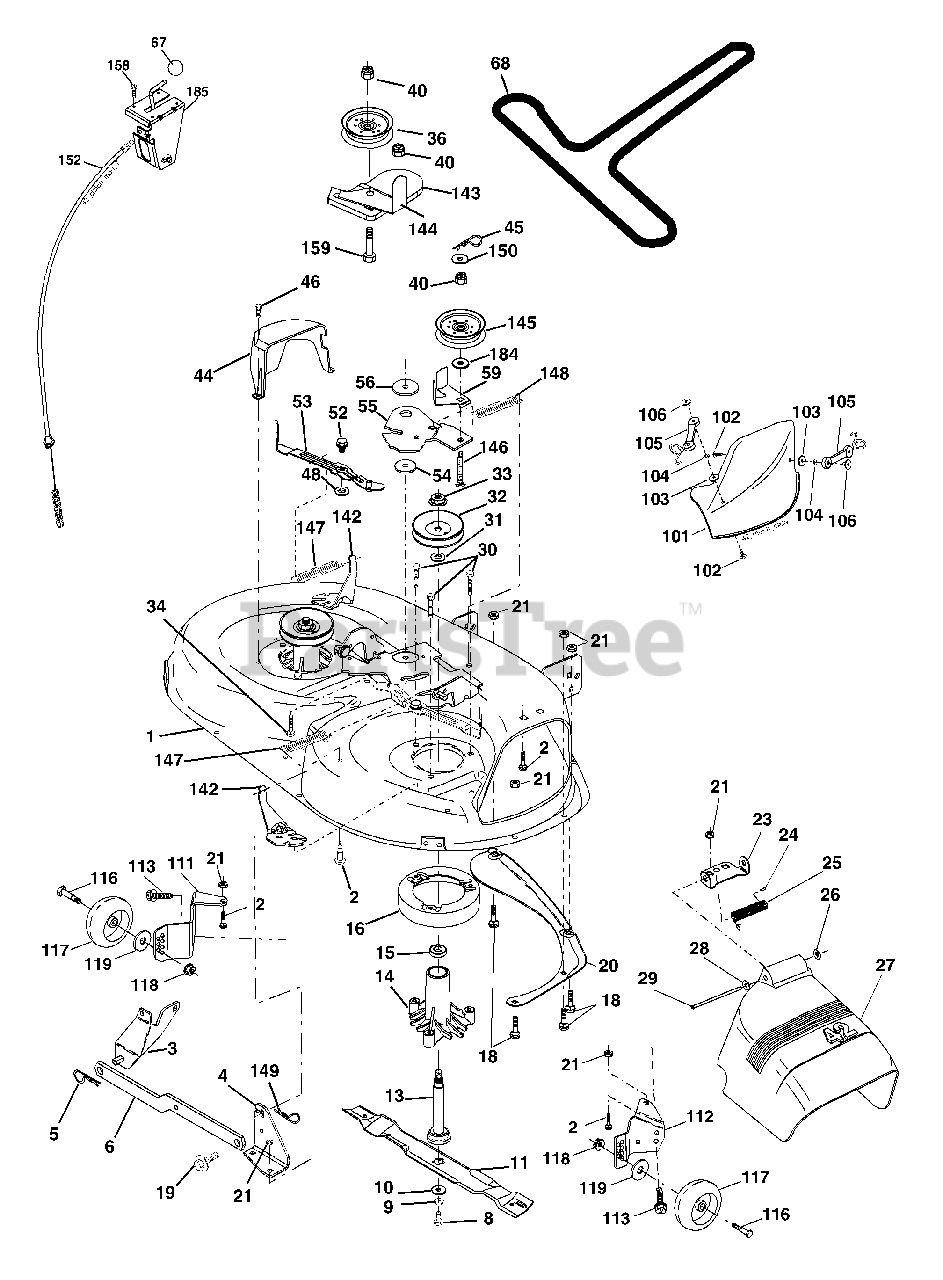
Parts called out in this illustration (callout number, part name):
1	Mower Deck Assembly, 42"
2	Bolt
3	Bracket Asm Fr. Sway Bar 3/42
4	Bracket Asm Deck 42" Sway Bar
5	Retainer Spring
6	Bar Sway Deck
8	Bolt 3/8-24 x 25 Gr. 8 patched
9	Washer, Lock
10	Washer, Hardened
11	Blade, 42" Mulching Std
11	Blade, 42" Mulching Premium
11	Blade, 42" Hi-Lift
13	Shaft Assembly, Mandrel, Vented
14	Housing, Mandrel, Vented
15	Bearing, Ball, Mandrel
16	Stripper, Mandrel Deck
18	Bolt, Carriage 5/16-18 x 5/8
19	Bolt, Shoulder
20	Baffle, Vortex
21	Nut
23	Bracket, Deflector Mower 42"
24	Cap, Sleeve 80 x 112 Blk Mower
25	Spring, Torsion, Deflector 2 52
26	Nut, Push Phos & Oil
27	Shield, Deflector 42" Blk
28	Washer 11/32 x 5/8 x 16 Ga.
29	Rod, Hinge 42" 6 75 W/G
30	Screw Thdrol Washer Head
31	Washer, Spacer Mower Vented
32	Pulley, Mandrel
33	Nut, Toplock 9/16 Flange
34	Bolt
36	Pulley, Idler, Flat
44	Guard, Mandrel, LH
45	Retainer
46	Screw, Thdrol 1/4-20 x 5/8 T
48	Washer, Hardened
52	Bolt, Shoulder 5/16-18 unc
53	Arm Assembly, Pad, Brake
54	Washer, Hardened
55	Arm, Idler
56	Spacer, Retainer
59	Guard TUV Idler
67	Knob
68	V-Belt, 42" Mower
92	Nut 3/8-16
101	Cover Mulching
102	Screw Pan Hd Phillip 10-24 x 5/8
103	Washer #10
104	Washer Lock #10
105	Latch Asm
106	Nut Weld
111	Bracket Wheel Guage LH
112	Bracket Wheel Gauge RH
113	Bolt 5/16-18
116	Bolt Shoulder
117	Wheel Guage
118	Nut Centerlock 3/8-16 unc
119	Washer 3/8 x 7/8 x 14 Ga.
129	Washer 13/32 x 13/16 x 12 Ga.
130	Bolt 3/8-16 x 1 Gr. 5
131	Bolt 3/8-16 x 1
142	Arm Spring Brake Mower
143	Bracket Arm Idler 42"
144	Keeper Belt 42" Clutch Cable
145	Pulley Idler Flat
146	Bolt Carriage Idler
147	Spring Extension
148	Spring Return Idler
149	Retainer Spring Yellow
150	Washer 9/32 x 3/4 x 10 Ga.
152	Clutch Cable 42"
158	Screw Hex Thd Cut 1/4-20 x 1/2
159	Bolt Rdhd Sqn 3/8-16 unc x 1-3/4
184	Washer 13/32 x 7/8 x 10 Ga.
185	Head Asm Cable Clutch
